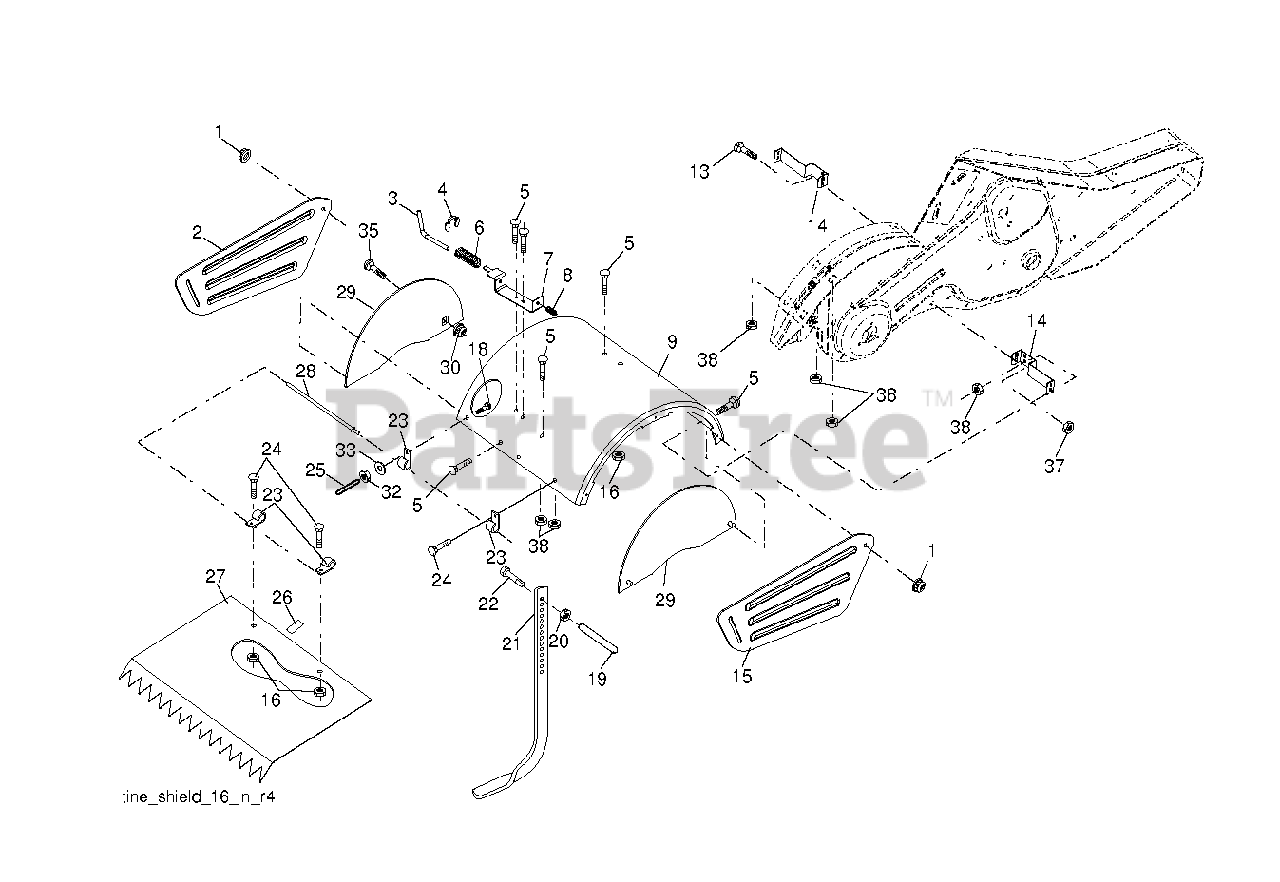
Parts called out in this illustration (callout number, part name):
1	NUT LOCK HEX FLANGE 5/16-18
2	SHIELD LH
3	STAKE PIN TI
4	RING, KLIP
5	BOLT, RDHD SQNK 5/16-18 X 3/4
6	SPRING TI
7	LATCH BRACKET TI
8	SHIELD,TINE**
9	SHIELD TINE
13	BOLT.CARRIAGE.5/16-18
14	BRACKET.TINE.SHIELD.TILLER.BLA
15	SIDE SHIELD RH
16	NUT T
19	GRIP CRT
20	NUT.HEX.3/8-16UNC
21	STAKE.DEPTH.16.CRT.BLACK
22	BOLT.375-16
23	HINGE CRT
26	PAD IDLER TI
27	SHIELD LEVELING
28	PIN.HINGE.TILLER
29	SHIELD.ASM.TILLER.SIDE.YELLOW
30	LOCKNUT-FLANGE 5/16-18
32	NUT
33	LOCKWASHER
35	BOLT
37	NUT.71038.31-18.HEX.NYLOCK
